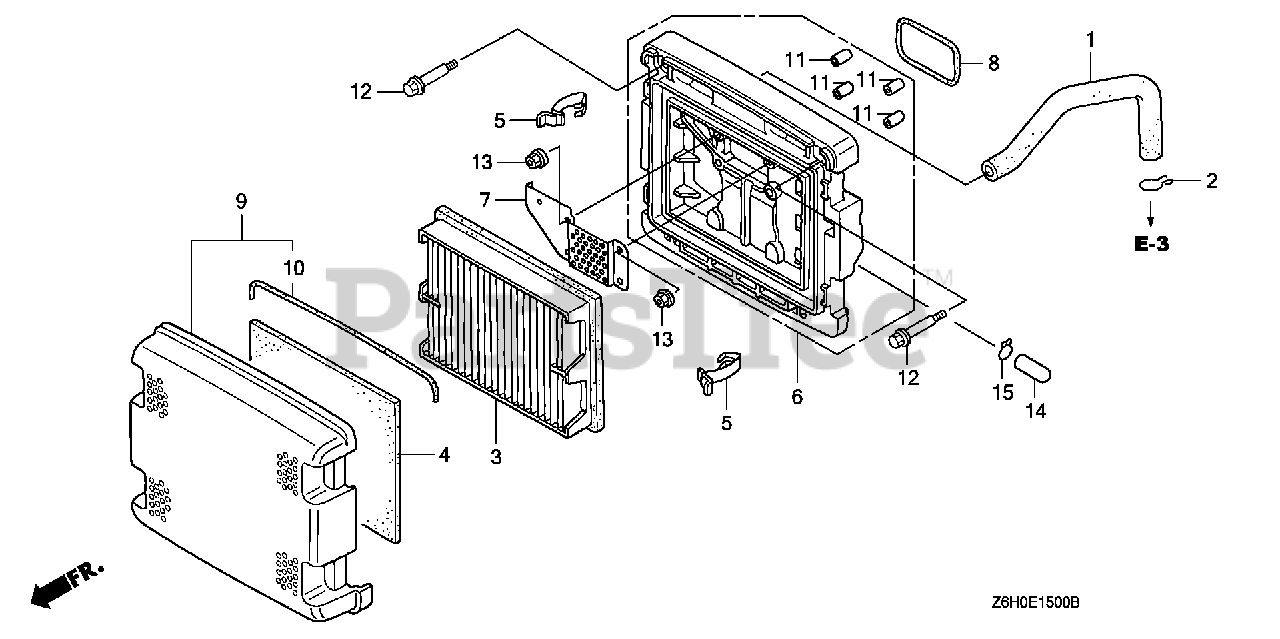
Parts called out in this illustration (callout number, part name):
1	TUBE, BREATHER
2	CLIP, BREATHER TUBE
3	ELEMENT, AIR CLEANER
4	FILTER (OUTER)
5	CLIP, AIR CLEANER
6	HOUSING, AIR CLEANER
7	CAP, AIR CLEANER
8	GASKET, AIR CLEANER
9	COVER ASSY., AIR CLEANER
10	SEAL, AIR CLEANER COVER
11	COLLAR A, AIR CLEANER
12	BOLT, SPECIAL (5MM)
13	NUT, FLANGE (6MM)
14	CAP, SEALING
15	CLIP, TUBE (B10)
